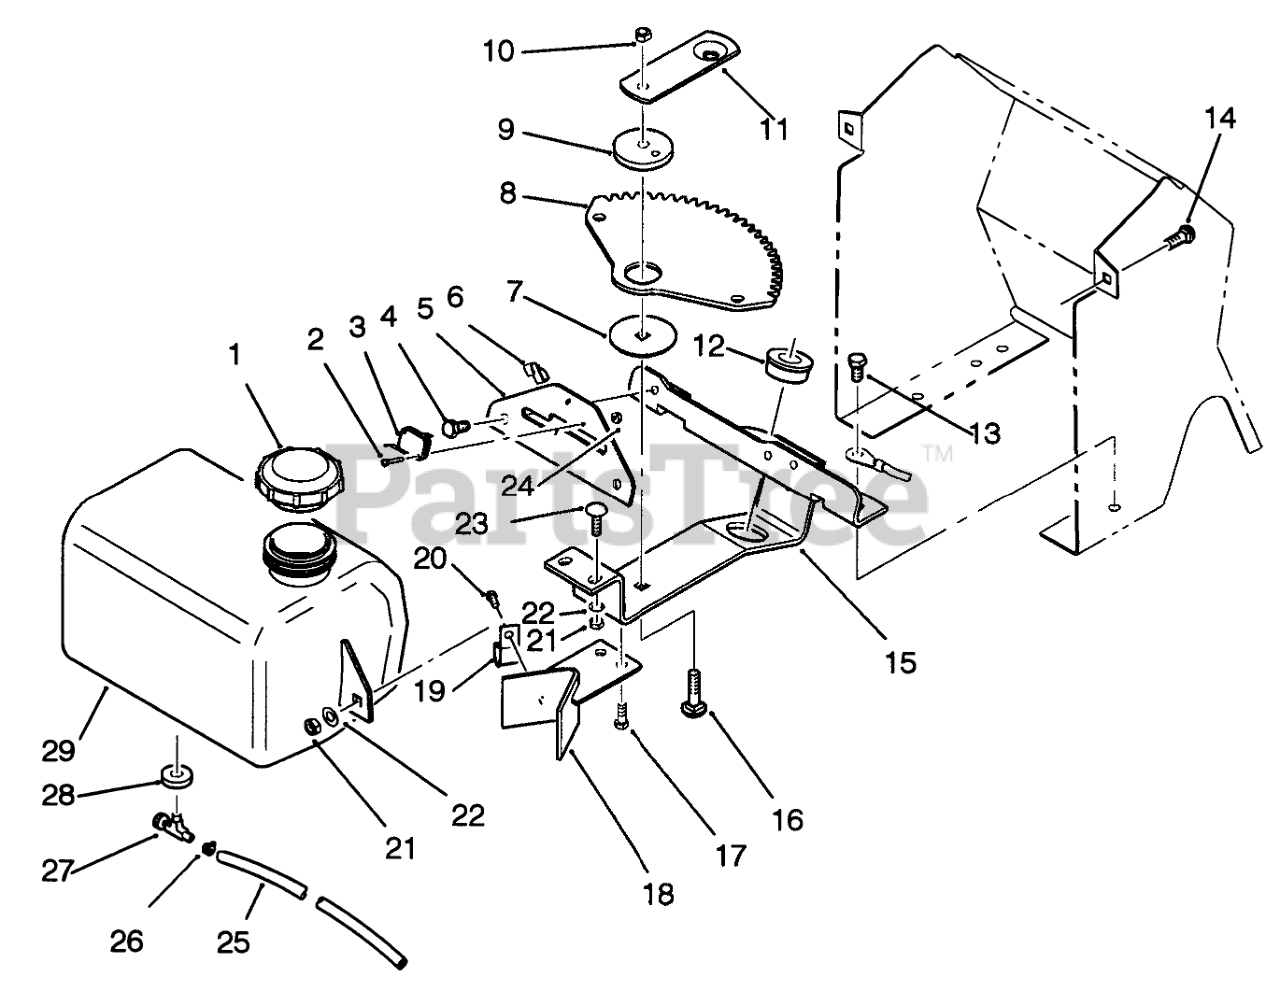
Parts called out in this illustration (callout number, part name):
1	CAP GAS
2	Screw
3	SWITCH - CLUTCH
4	Screw
5	PLATE SHIFT R
6	CLIP-CABLE
7	WASHER-BEARING
8	GEAR-SECTOR
9	BUSHING
11	Plate
12	BEARING-WHEEL
13	SCREW
14	SCREW-CARR
15	STEERING BRKT - W/A R
16	SCREW-CARR
17	Screw
18	Stop
19	CLIP
20	Screw
21	NUT-LOCK, NI
22	WASHER-PLAIN
23	Bolt-Carriage
24	NUT HEX 4-40 ELAST
25	S/A FUEL HOSE 6554
26	CLAMP-HOSE
27	VALVE-FUEL
28	BUSHING
29	Fuel Tank
